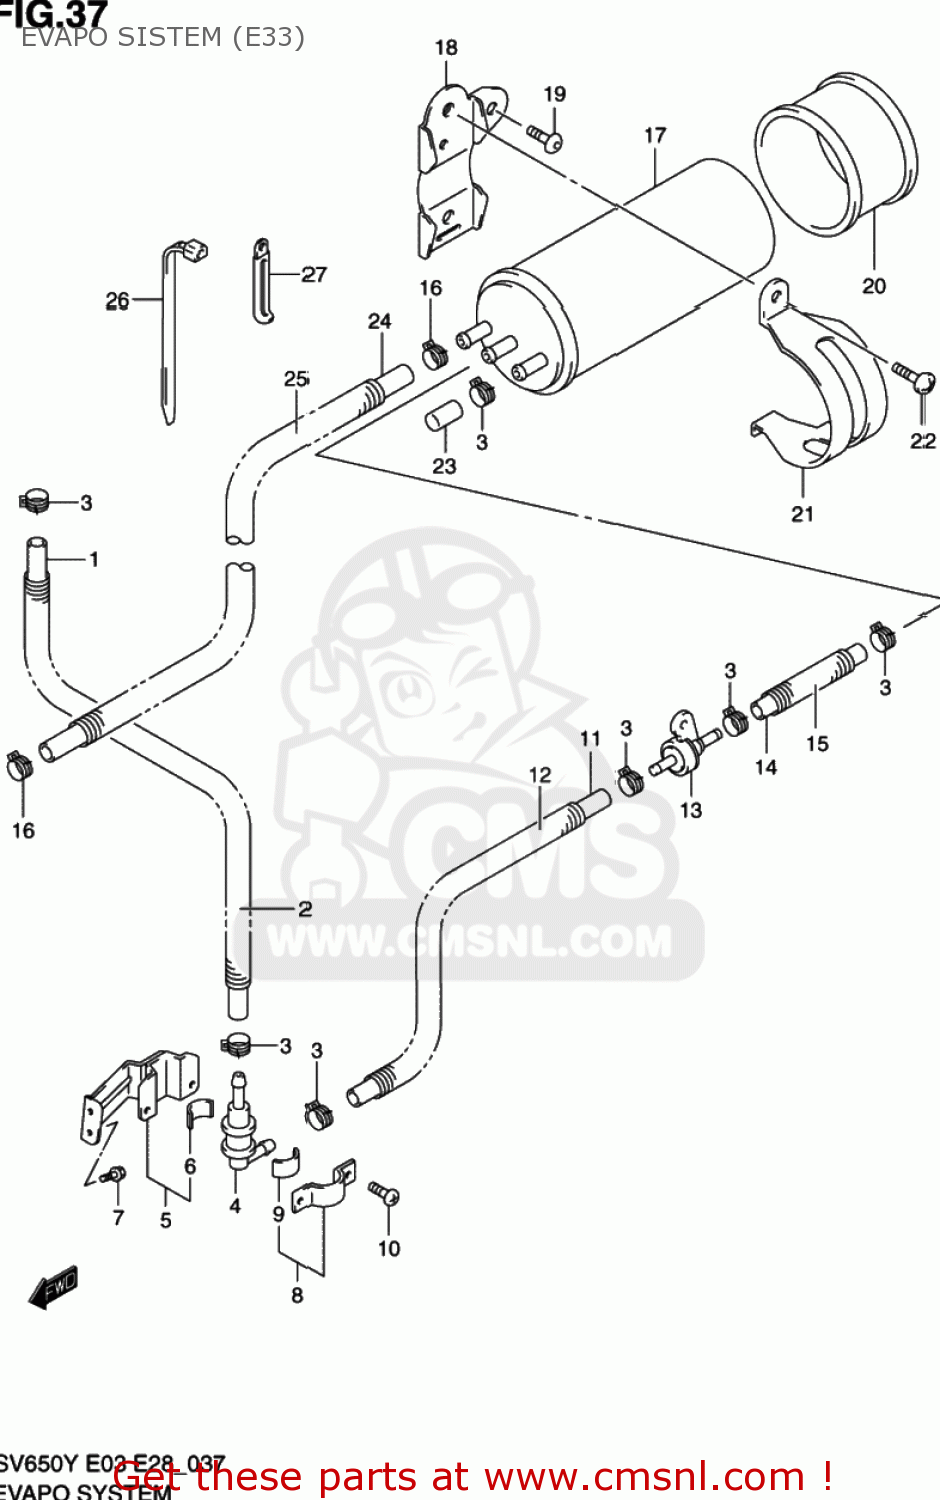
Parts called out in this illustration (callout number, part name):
1	HOSE,TANK & BREATHER VALVE
2	PROTECTOR(14.5X15.5X600)
3	CLIP
4	VALVE,FUEL TANK BREATHER
5	PLATE,BREATHER VALVE
6	CUSHION
7	BOLT
8	PLATE,FUEL TANK BREATHER NO.2
9	CUSHION
10	SCREW
11	HOSE,VALVE & CANISTER
12	PROTECTOR(14.5X15.5X600)
13	VALVE,2 WAY & BREATHER VALVE
14	HOSE(5.4X11.4X600)
15	PROTECTOR(14.5X15.5X600)
16	CLIP
17	CANISTER ASSY,CHARCOAL
18	BRACKET,CANISTER
19	SCREW(6X16)
20	CUSHION,CANISTER
21	HOLDER,CANISTER
22	SCREW 6X12
23	CAP,OD:11.5
24	HOSE(5.4X11.4X760)
25	HOSE
26	CLAMP(L:165)
27	CLAMP(L:80 T:1.0)
